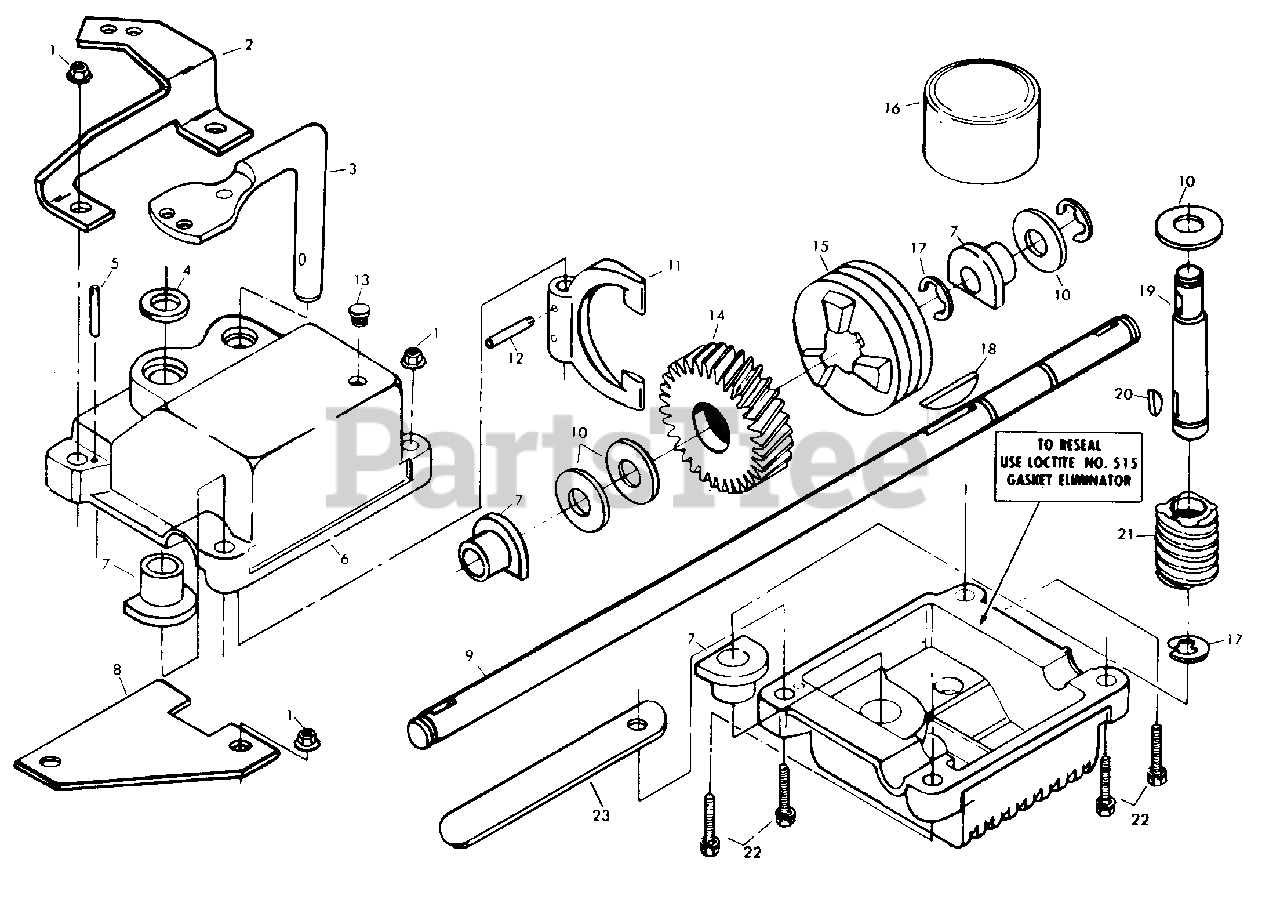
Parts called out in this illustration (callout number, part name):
1	Keps Locknut (AYP part number)
2	Adjusting Bracket (AYP part number)
3	Shifter Assembly (AYP part number)
5	Grooved Pin (AYP part number)
6	Gear Case Halves (Inc. Upper & Lower Halves) (AYP part number)
7	Bearing (AYP part number)
8	Spring Bracket (AYP part number)
9	Drive Shaft (AYP part number)
10	Hardened Washer (AYP part number)
11	Yoke Clutch (AYP part number)
12	Grooved Pin (AYP part number)
13	Plug (AYP part number)
14	Helical Gear (AYP part number)
15	Jaw Clutch (AYP part number)
16	Grease (AYP part number)
17	E-Ring (AYP part number)
18	Hi-Pro Key (AYP part number)
19	Worm Shaft (AYP part number)
20	Woodruff Key #3 (AYP part number)
21	Worm (AYP part number)
22	Hex Head Mach. Screw (AYP part number)
23	Identification Tag
